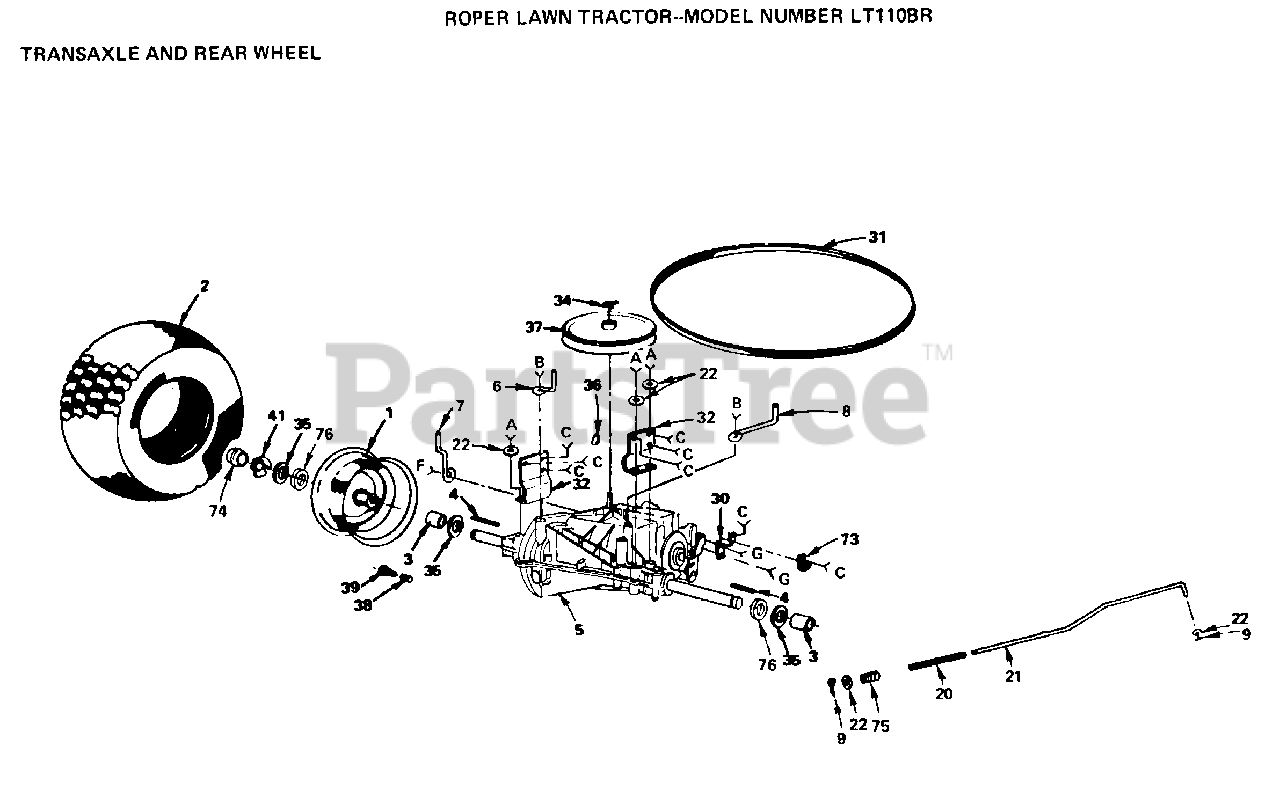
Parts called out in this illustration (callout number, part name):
3	WHEEL SPACER LT
6	BELT SNUBBER T
9	COTTER PIN
22	WASHER
30	STRAP - TORQUE
34	KLIP RING
37	PULLEY-INPUT LT
38	VALVE CAP
39	VALVE STEM LT
41	E-RING LT
73	INSUL CLIP T
74	HUB CAP
75	SPRING T
76	WASHER LT
